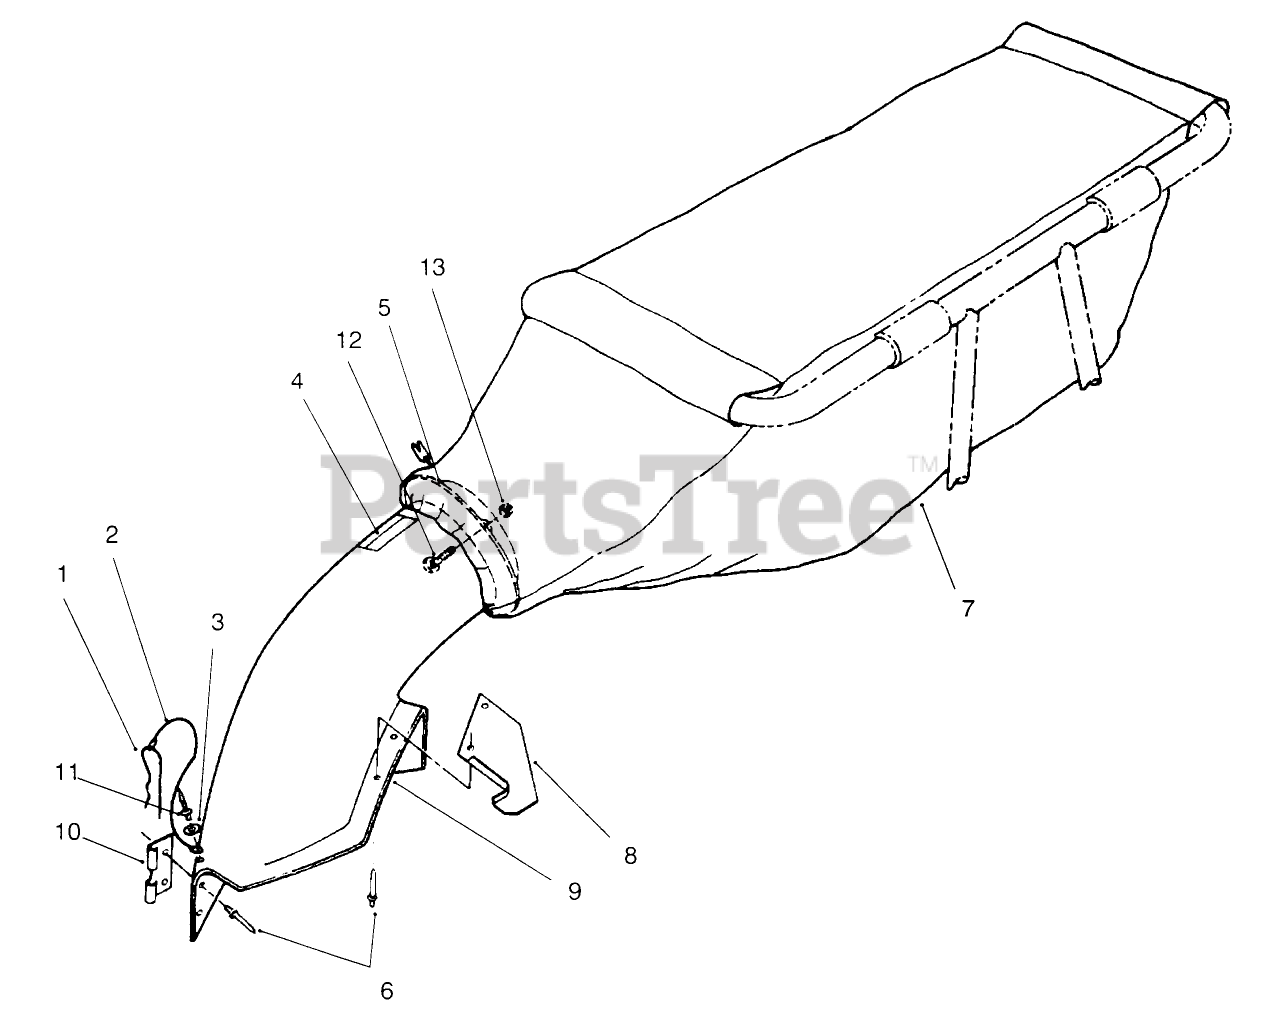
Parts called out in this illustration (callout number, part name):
1	PIN-LOCKING, CHUTE
2	LANYARD
3	WASHER-PLAIN
4	DECAL-DANGER
5	Ring-Bagger
6	RIVET-BLIND
7	BAG ASSEMBLY
8	CHUTE SUPT BRKT
9	Chute Assembly (Incl. Ref. #1-6, & 8, 10-13)
10	BRACKET-MOUNTING, CHUTE
11	RIVET-BLIND
12	SCREW-CARR
13	NUT-LOCK, NI
